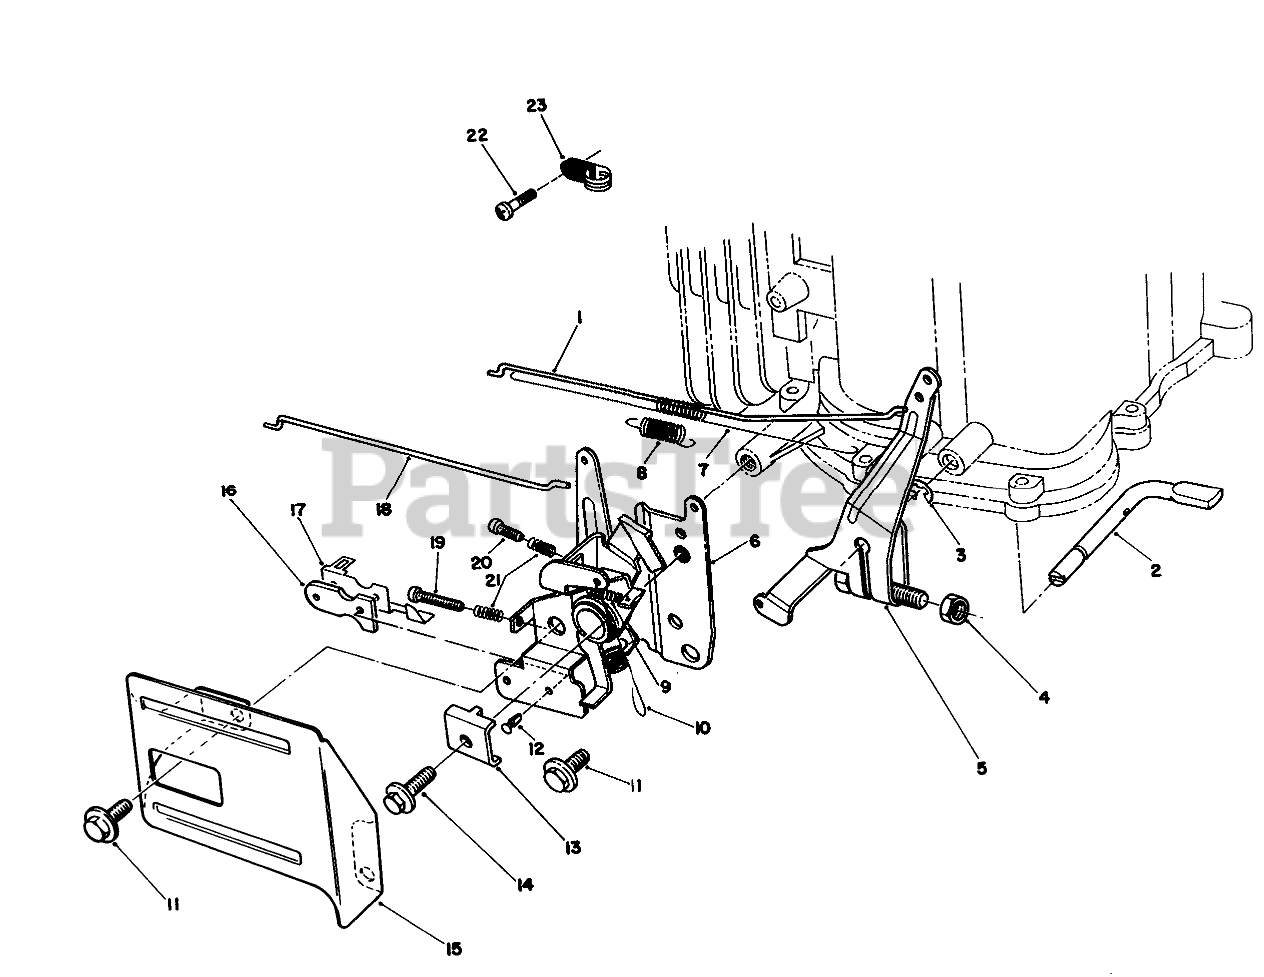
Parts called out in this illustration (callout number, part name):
1	Rod-Carburetor
2	SHAFT
3	E-RING
5	ARM ASM
6	THROTTLE
7	SPRING
8	SPRING
9	SPRING
10	SPRING
12	RIVET
13	CLAMP-CABLE
15	THROTTLE GUARD
16	INSULATOR-KILL SWITCH
17	TERMINAL-KILL SWITCH
18	Rod-Choke
19	SCREW
20	SCREW
21	SPRING
22	SCREW
23	Clamp
